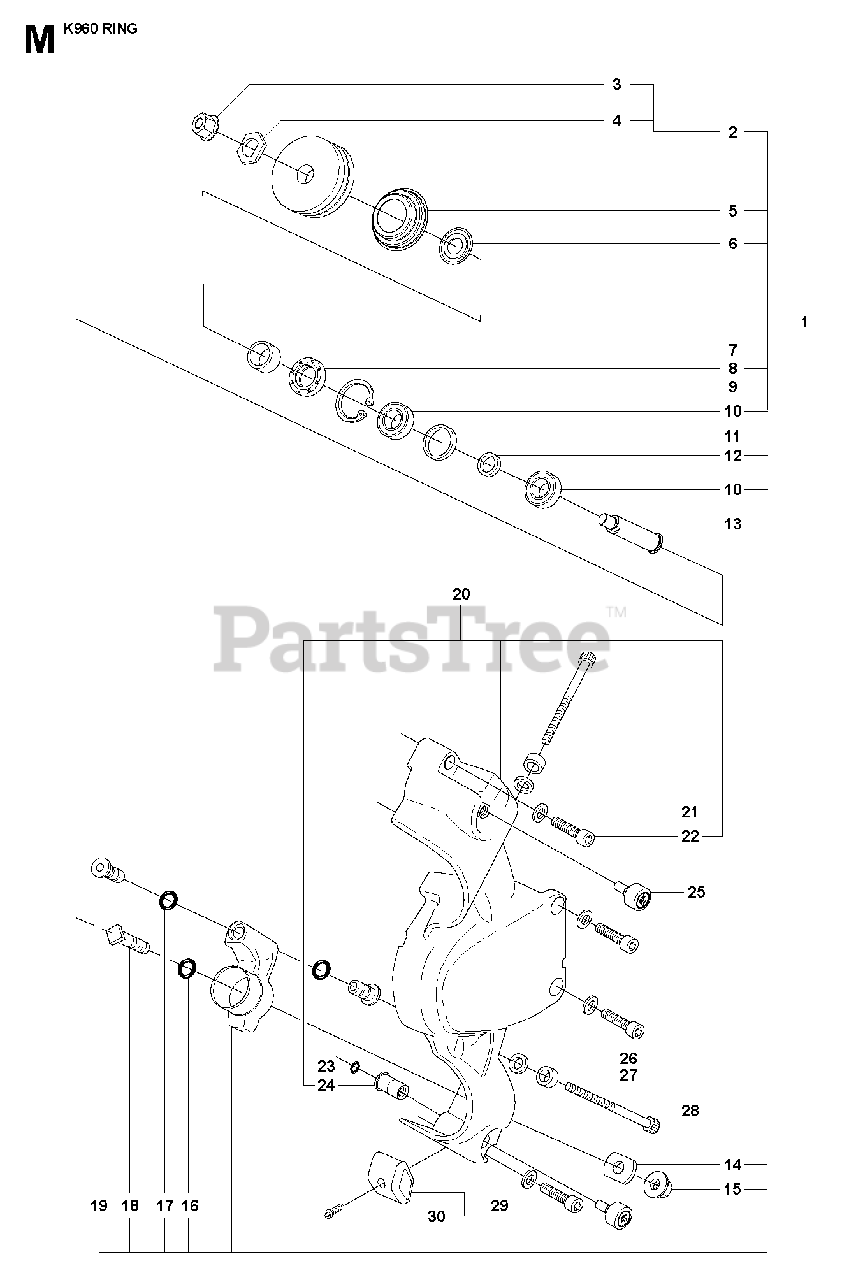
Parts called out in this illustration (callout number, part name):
1	LEVER ASSYIncl. 2, 5 - 18
2	SUPPORT ROLLERIncl. 3, 4
3	NUTFine thread
10	BALL BEARING
29	WEAR PROTECTIONIncl. 29
